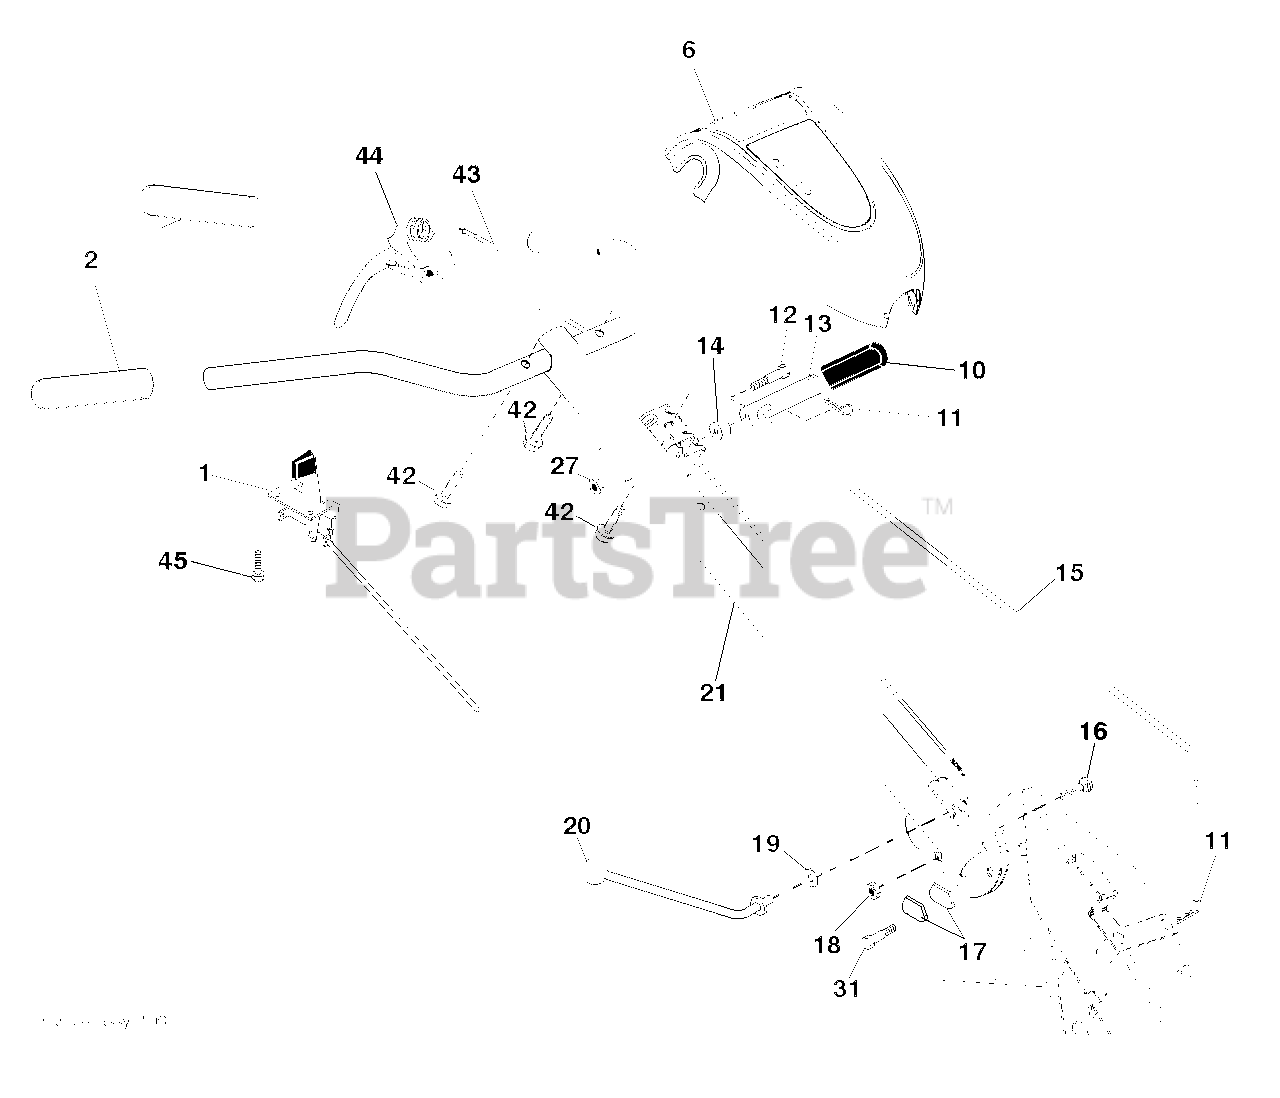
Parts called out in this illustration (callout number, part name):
1	CONTROL.THROTTLE.47.W/Z.BEND
2	GRIP.1X5.06
6	CONSOLE.GREY.W/THROT.TR430.DUA
10	GRIP T
11	RETAINER M
12	SHOULDER BOLT ST
13	HANDLE.SHIFT.TILLER.498
14	GROMMET.RUBBER.CRT.TILLER
15	ROD.SHIFT.YARD PRO.UNIVERSAL.
16	BOLT D
17	LOCK.HANDLE.CRT
19	WASHER CRT
20	LEVER.LOCK.CRT
21	HANDLE.ASM.HUSQ/P.PRO.GREY
27	NUT T
31	BOLT.PIVOT
42	SCREW.#10 X 0.750.BOS
43	CABLE.HANDLE.TINE.CONTROL.CE
44	CONTROL.HANDLE.TWO.FUNCTION.CE
45	SCREW.#10 X 0.500
